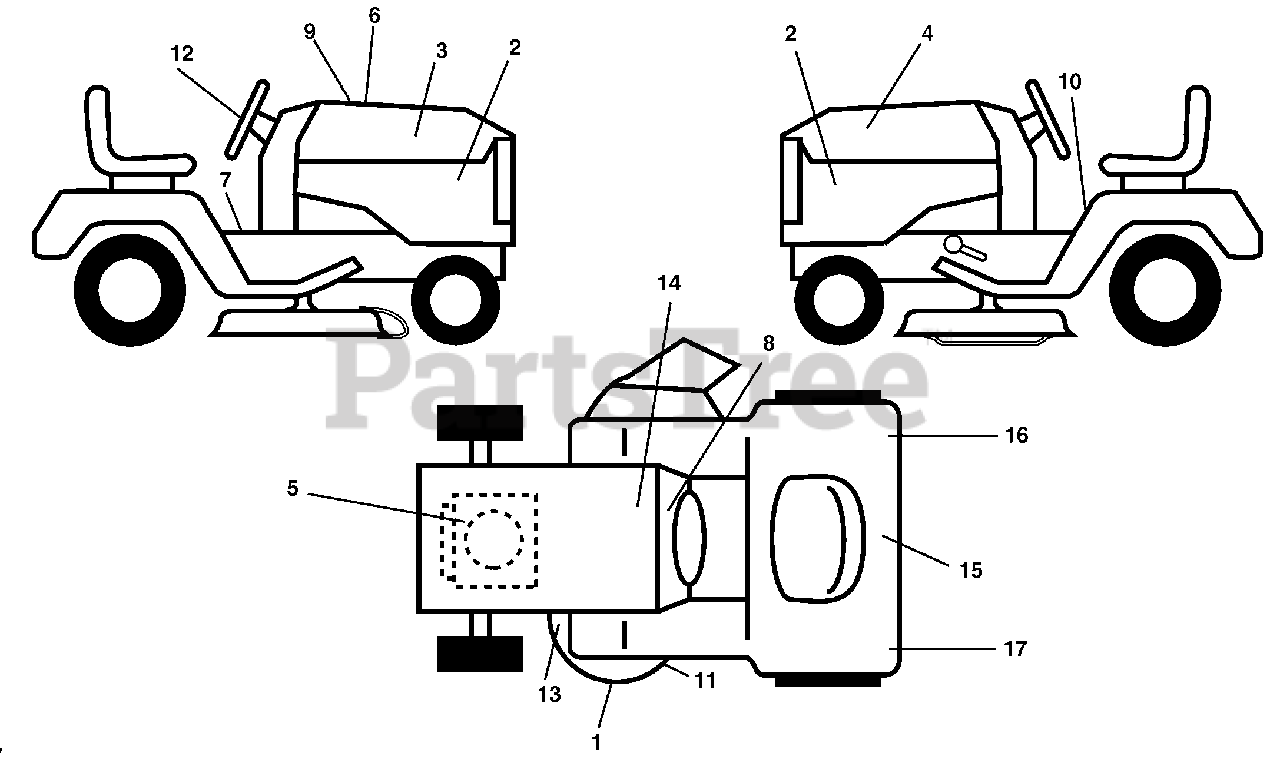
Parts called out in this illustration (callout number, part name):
1	Decal Deck Hvy Duty
2	Decal Panel Side
3	Decal Hood RH
4	Decal Hood LH
5	Decal HP Engine
6	Decal Hood Cust. Resp.
7	Decal Operator
8	Decal Dash
9	Decal Replacement
10	Decal Fender Danger
11	Decal V-Belt Sch.
12	Decal Wheel Steering
13	Decal Deck Caution
14	Decal Bat Dan/Psn
15	Decal Fender
16	Decal Reflector RH
17	Decal Reflector LH
